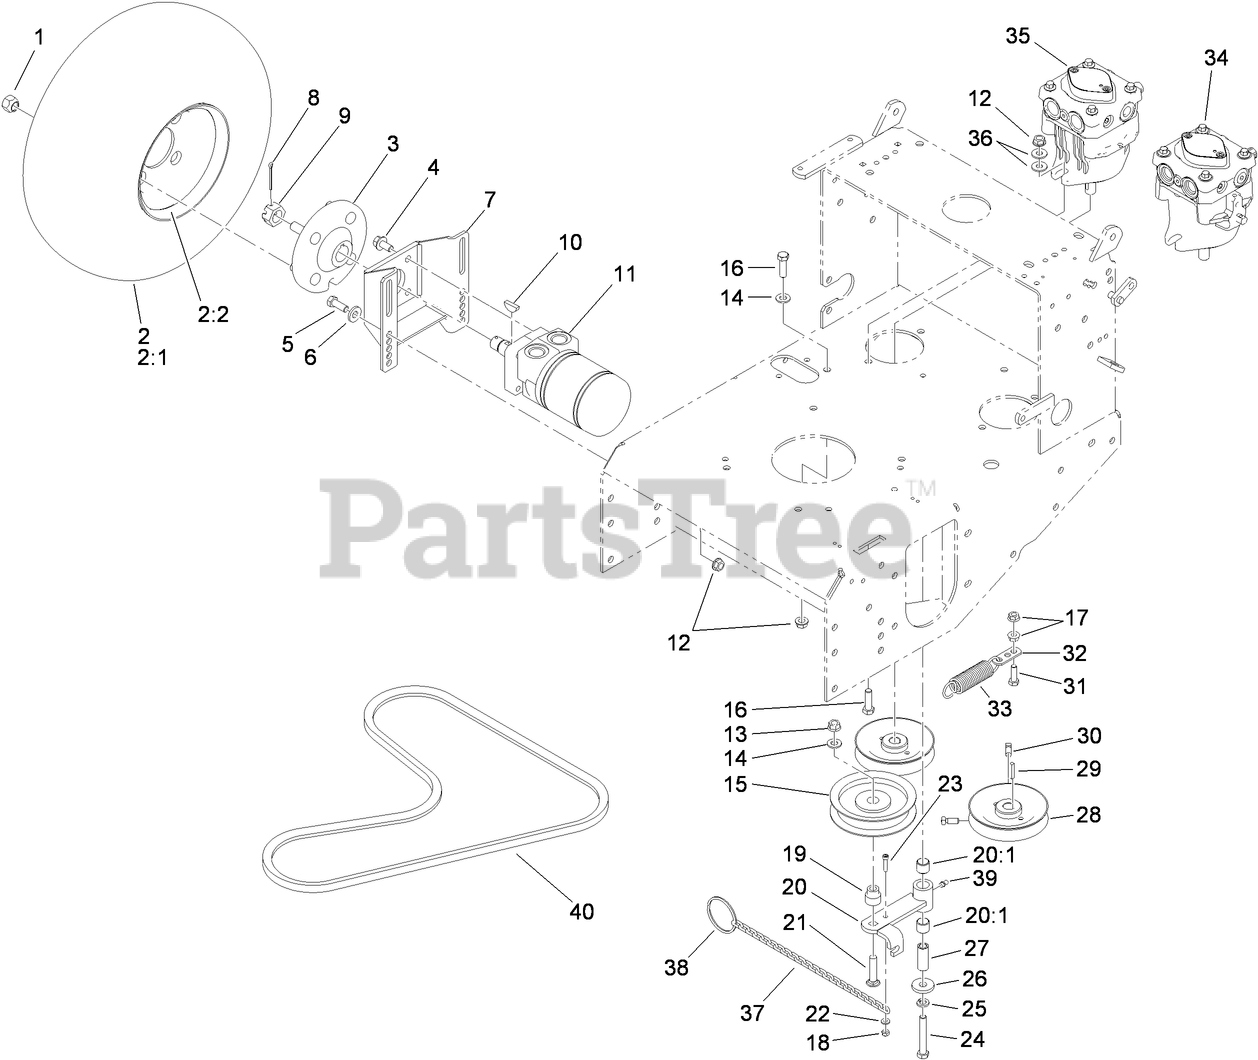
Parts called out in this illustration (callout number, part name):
1	NUT-LUG
2	WHEEL AND TIRE ASM
2:1	TIRE-TURFMASTER
2:2	Wheel-Rim
3	WHEEL HUB ASM
4	SCREW-HHF
5	SCREW-HH
6	WASHER-BELLEVILLE
7	MOUNT-MOTOR
8	PIN-COTTER
9	NUT-HEX, SLOTTED
10	Key-Woodruff
11	HYD MOTOR ASM
12	NUT-HHF, WHIZ
13	NUT-HF
14	WASHER-FLAT
15	PULLEY-IDLER
16	SCREW-HH
17	NUT-HF
18	NUT-LOCK, NI
19	BUSHING-IDLER
20	Idler Arm ASM
20:1	SLEEVE-BEARING
21	SCREW-CARR
22	WASHER-FLAT
23	SCREW-HSH
24	SCREW-HH
25	WASHER-LOCK
26	WASHER
27	BUSHING
28	SHEAVE ASM
30	SCREW-SET
31	SCREW-HH
32	Anchor-Spring
33	SPRING-EXTENSION
34	LH HYD PUMP ASM
35	RH HYD PUMP ASM
36	WASHER-FLAT
37	Chain-Link, Twist
38	Ring-Split
39	FITTING-GREASE
40	V-BELT
